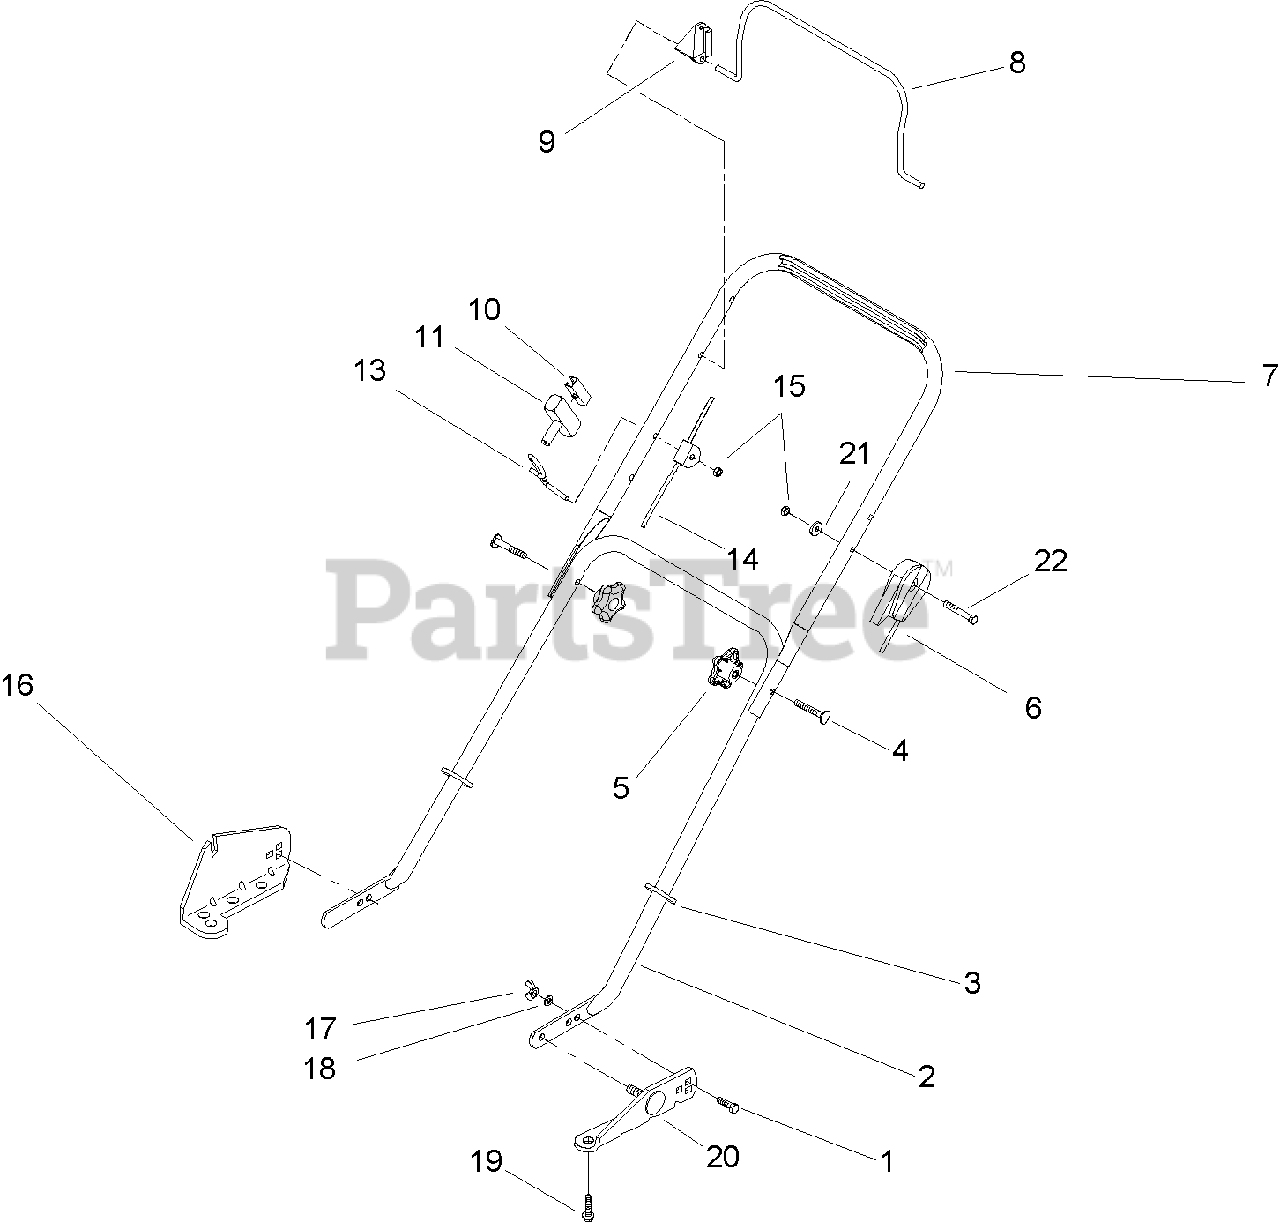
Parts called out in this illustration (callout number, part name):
1	SCREW-CARR
2	Handle Section-Lower
3	STRAP-TIE
5	KNOB-HANDLE
6	CABLE - THROTTLE
7	HANDLE - UPPER
8	BAIL-BRAKE
9	STOP-PIVOT
10	CLIP-STARTER
11	HANDLE-START
13	GUIDE-ROPE
14	CABLE - FLYWHEEL BRAKE
15	NUT-LOCK, NI
16	RH BRACKET and PIN ASM
18	WASHER-LOCK
20	LH BRACKET and PIN ASM
21	WASHER
22	SCREW-HH
